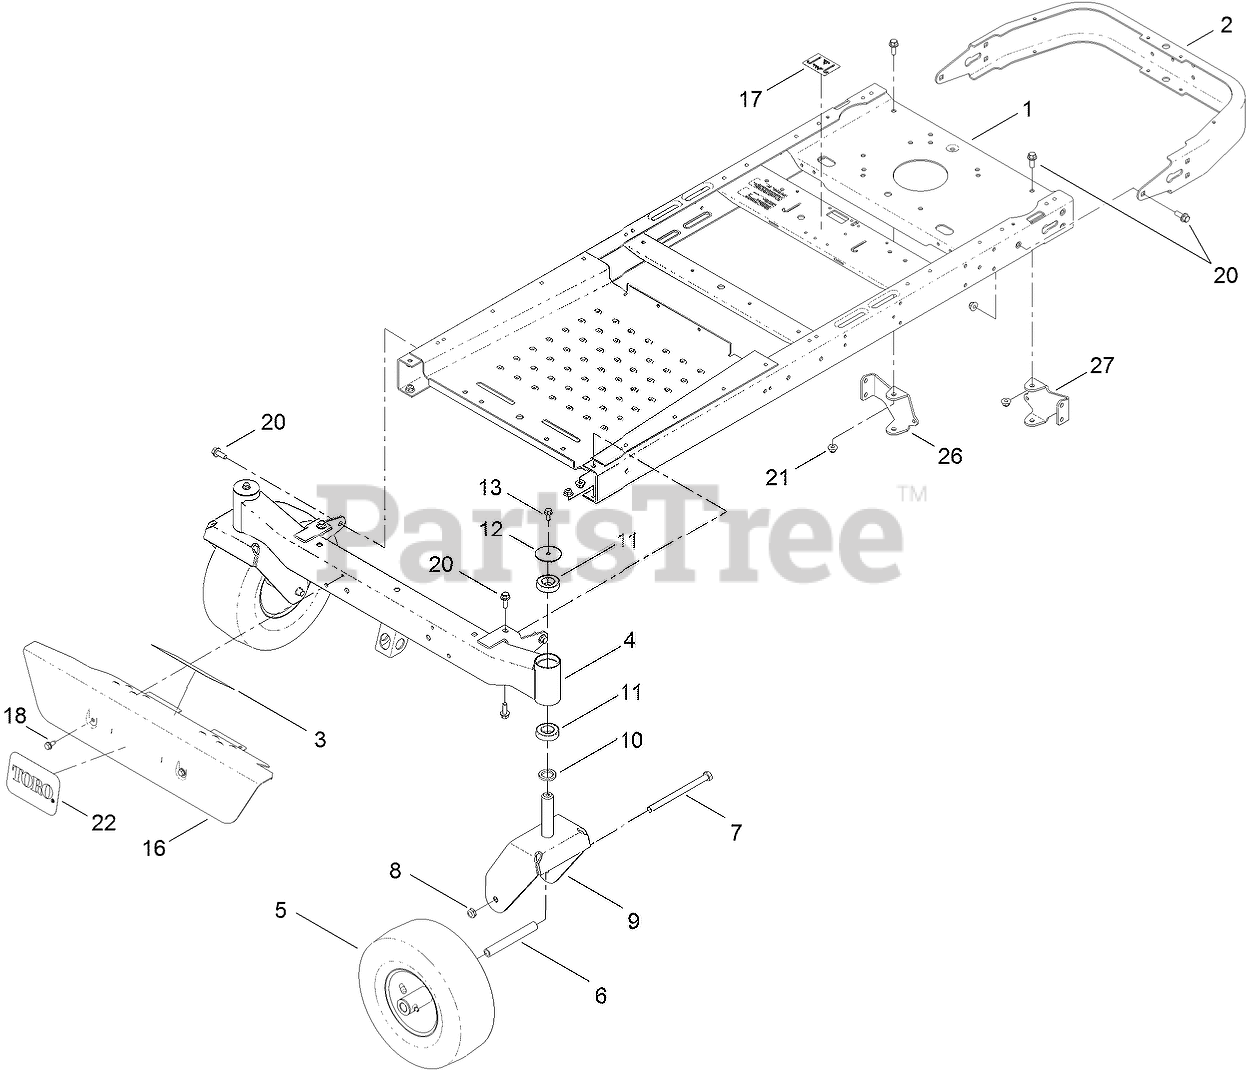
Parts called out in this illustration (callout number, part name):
1	FRAME ASM
2	BUMPER-REAR (WIDE)
3	DECAL-DANGER
4	AXLE-FRONT, WIDE
5	13 INCH WHEEL AND TIRE ASM
6	SPANNER
7	SCREW-HH
8	NUT-LOCK, NI
9	FORK-CASTER
10	WASHER-THRUST
11	BEARING-BALL
12	WASHER
13	SCREW-HHF
16	FOOTREST
17	DECAL-TRANSPORT
18	SCREW-HWHTF
20	SCREW-HHF
21	NUT-HF, NI
22	DECAL
26	MOUNT-HYDRO, REAR (RH)
27	MOUNT-HYDRO, REAR (LH)
